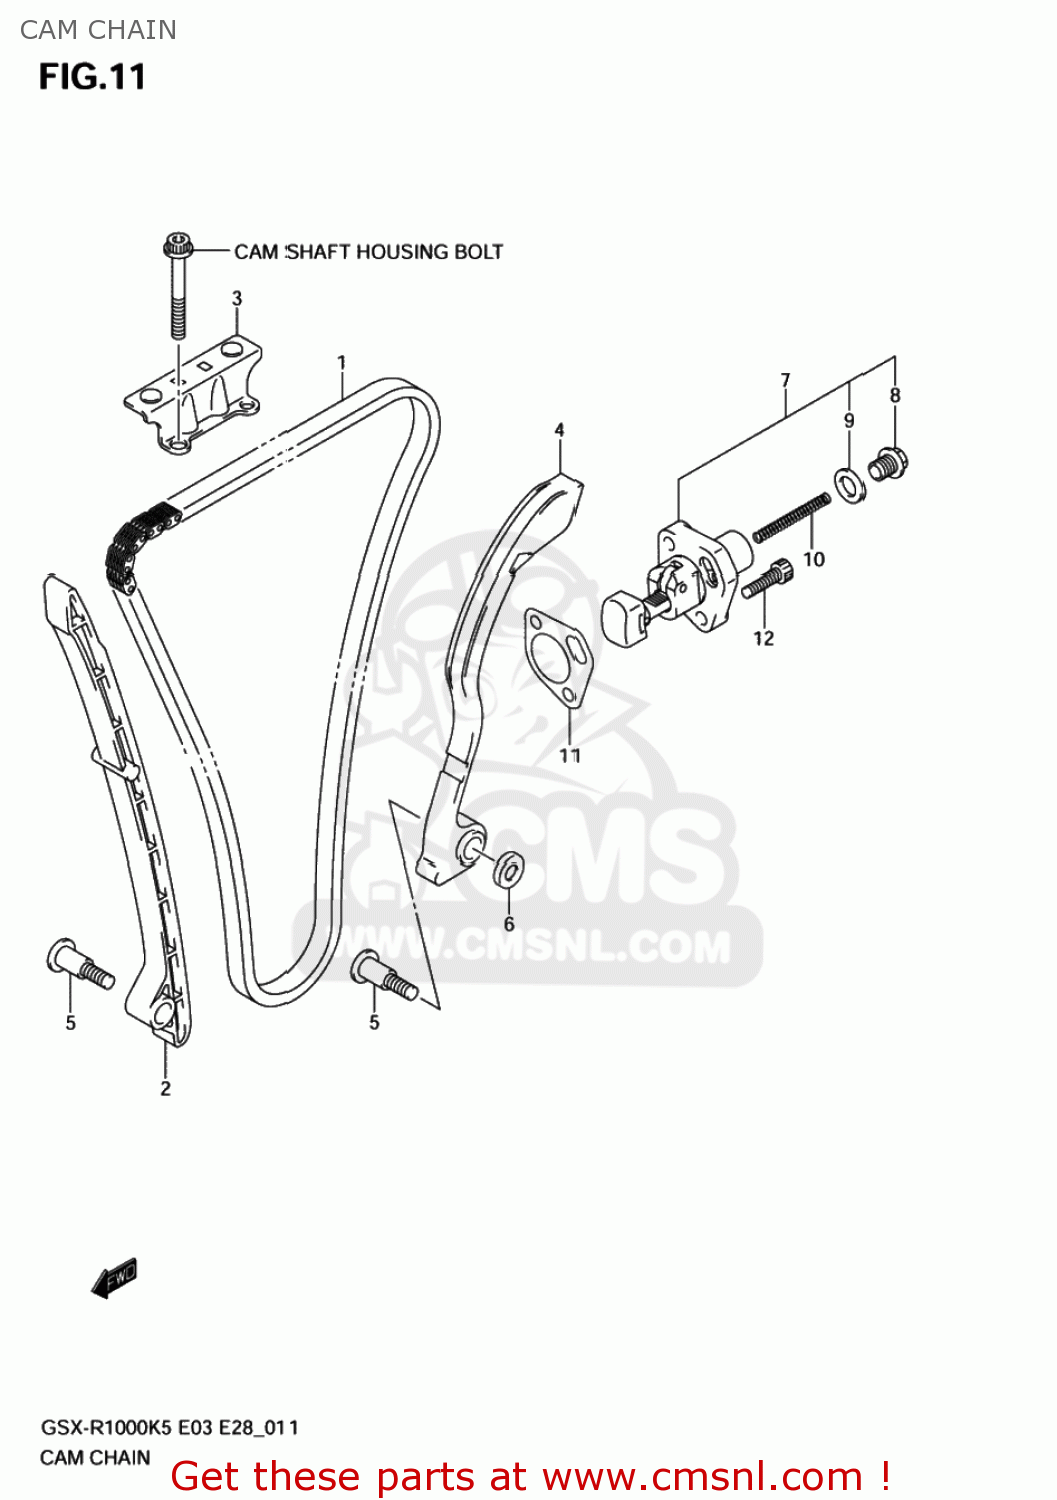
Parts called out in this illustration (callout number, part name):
1	CHAIN COMP,CAM
2	GUIDE,CAM CHAIN NO.1
3	GUIDE CAM CHAIN NO,2
4	TENSIONER,CAM CHAIN
5	BOLT,CAM CHAIN TENSIONER/GUIDE
6	WASHER,CAM CHAIN TNSN
7	ADJUSTER ASSY,TENSIONER
8	PLUG,FR TENSIONER ADJ
9	GASKET,TENSIONER ADJUSTER (NAS)
10	SPRING
11	GASKET,TENSIONER ADJUSTER (NAS)
12	BOLT,CL.COVER
